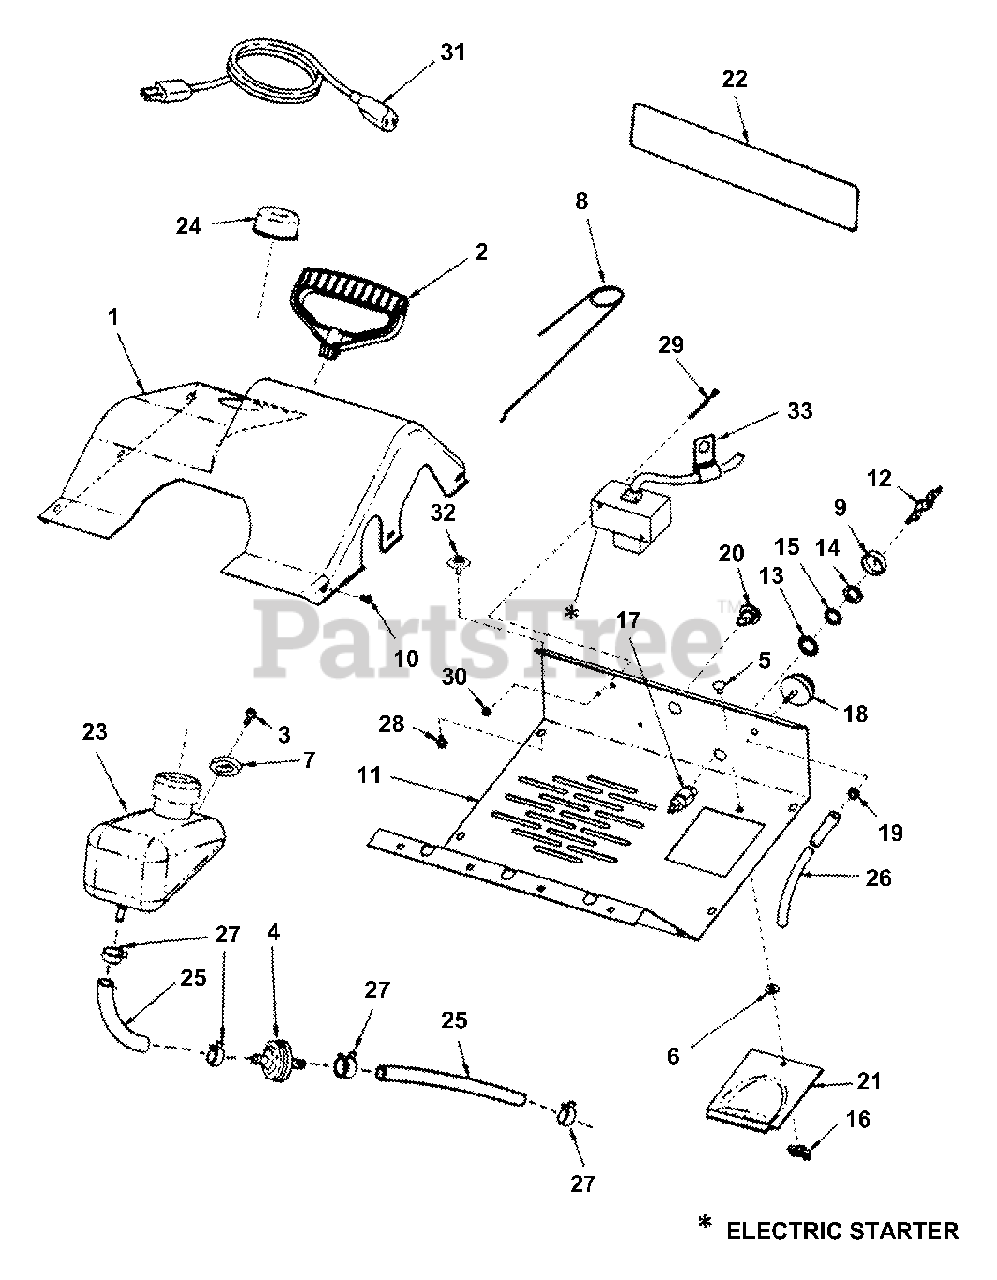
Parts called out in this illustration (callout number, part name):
1	COVER, Top
2	HANDLE, Rope Starter (Mitten) (Tecumseh # 178-223)
3	SCREW, 1/4-20 x 3/4" Self-Tapping (Torx)
4	FILTER, Fuel (In-Line)
5	BOLT, 1/4-20 x 3/4" Short Neck Carriage, Grade 5
6	RETAINER, 1/4" Bolt
7	ISOLATOR, Fuel Tank/Cover
8	CONTROL, Choke
9	BEZEL
10	SCREW, #10-24 x 1/2" Hex Washer Self-Tap (Sems)
11	PANEL, Bottom
12	KEY, Ignition
13	WASHER, 5/8" Internal Tooth Lock
14	NUT, 5/8-32 Hex (Special)
15	SPACER
16	NUT, 1/4-20 Wing (Black Nylon)
17	SWITCH, Ignition
18	PRIMER, Fuel
19	NUT, 1/4-20 Hex Flange Lock
20	GUIDE, Rope
21	COVER, Carburetor
22	DECAL, Control Panel
23	TANK, Fuel
24	CAP, Fuel Tank
25	LINE, Fuel
26	HOSE, Primer
27	CLAMP, Fuel Line
28	SCREW, 1/4-20 x 3/8" Hex Washer Self-Tap
29	SCREW, #6-32 x 2-1/2" Hex Head Cap (Electric Start only)
30	NUT, #6-32 Hex (Keps) (Electric Start only)
31	CORD, Extension (10 Ft.)(Electric Start only) (Tecumseh # 1A174-17 or 32450B)
32	SCREW, #10-24 x 1/2" Hex Washer Self-Tap (Sems)
33	WIRE CLAMP, Vinyl Covered
